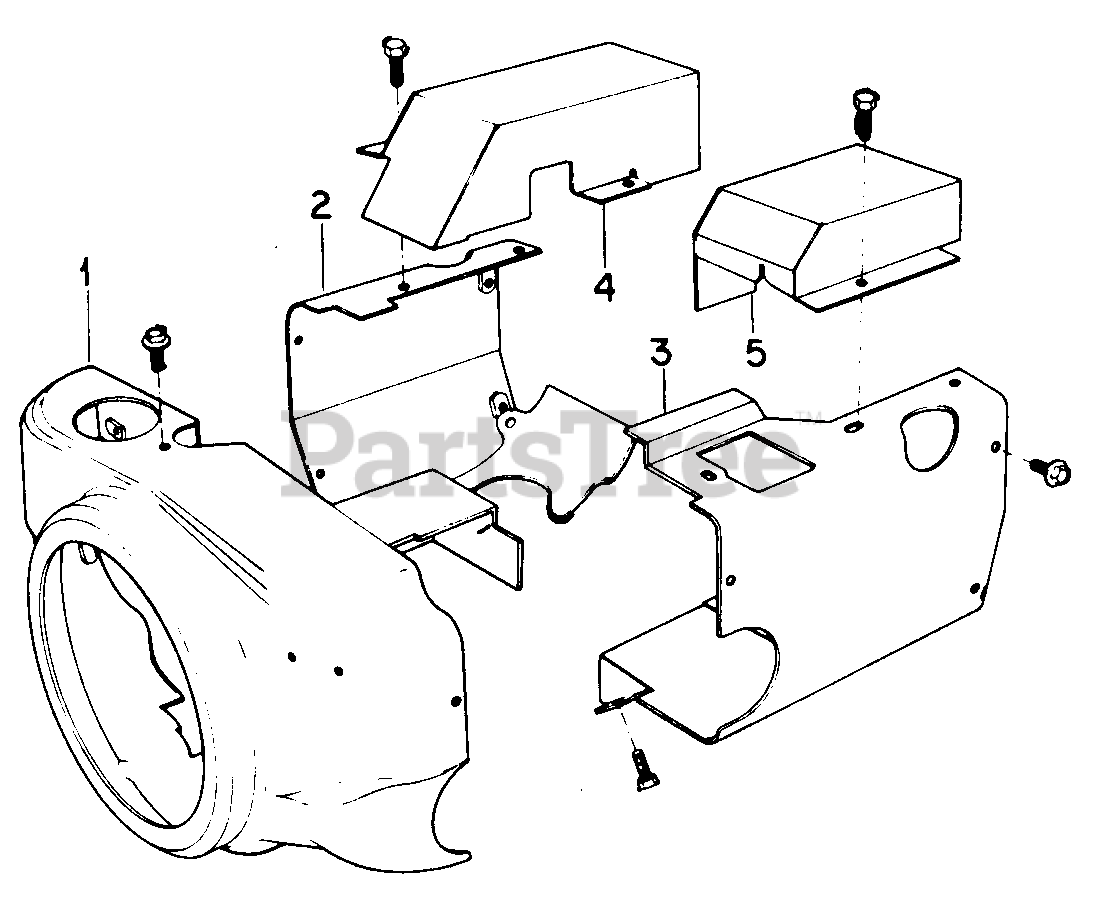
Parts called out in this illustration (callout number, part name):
1	Housing, Blower
2	Housing, Cylinder Air, LH
3	Housing, Cylinder Air, RH
4	Cover, Exhaust Tube, LH
5	Cover, Exhaust Tube, RH
